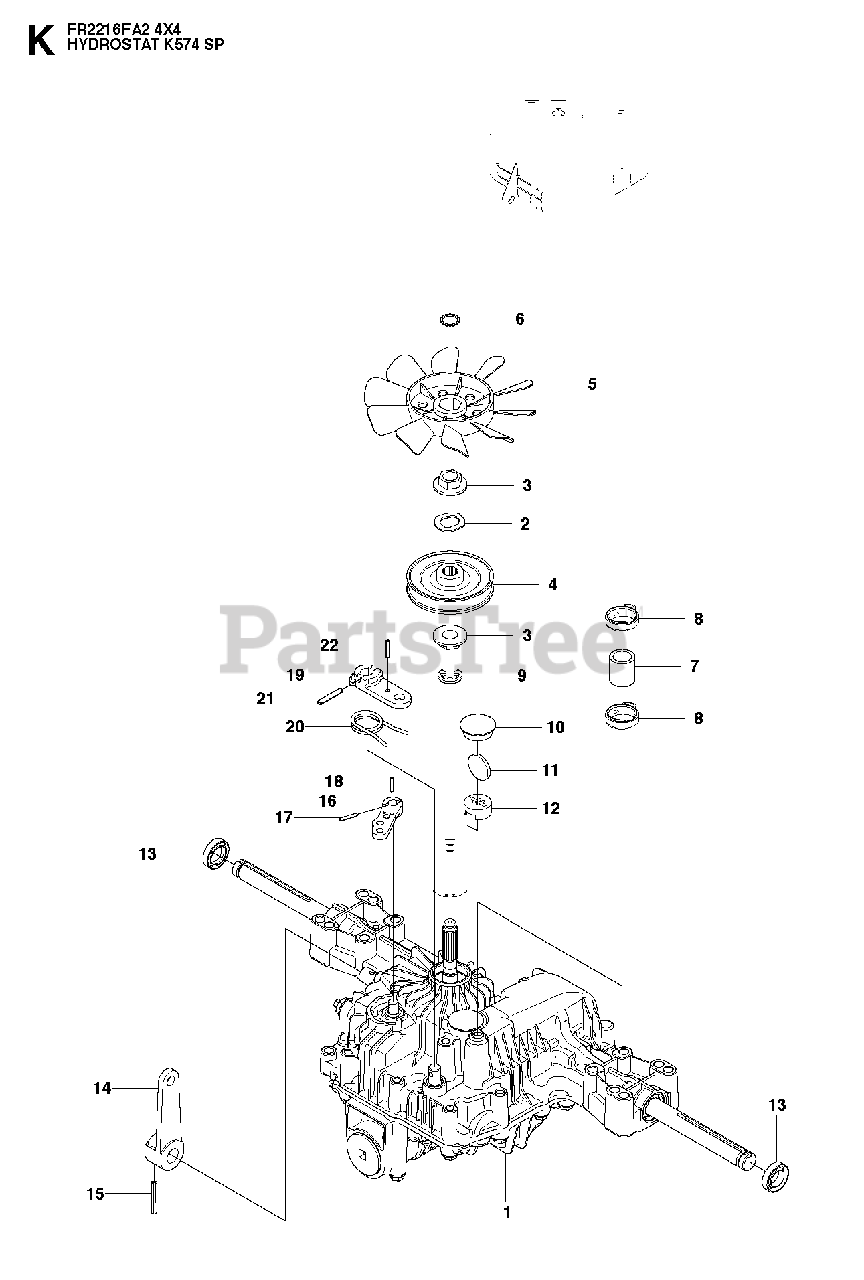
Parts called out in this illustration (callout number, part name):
1	HYDRAULMOTOR
2	WASHER **
5	FAN
6	RETAINING RING **
8	CLAMP
9	CLIP
10	PLUG
11	MAGNET
12	MAGNET HOLDER
13	SEALING
14	CONTROL LEVER
15	PIN
16	ARM
17	PIN
18	PIN
19	ARM
20	RETURN SPRING
21	PIN
22	PIN
